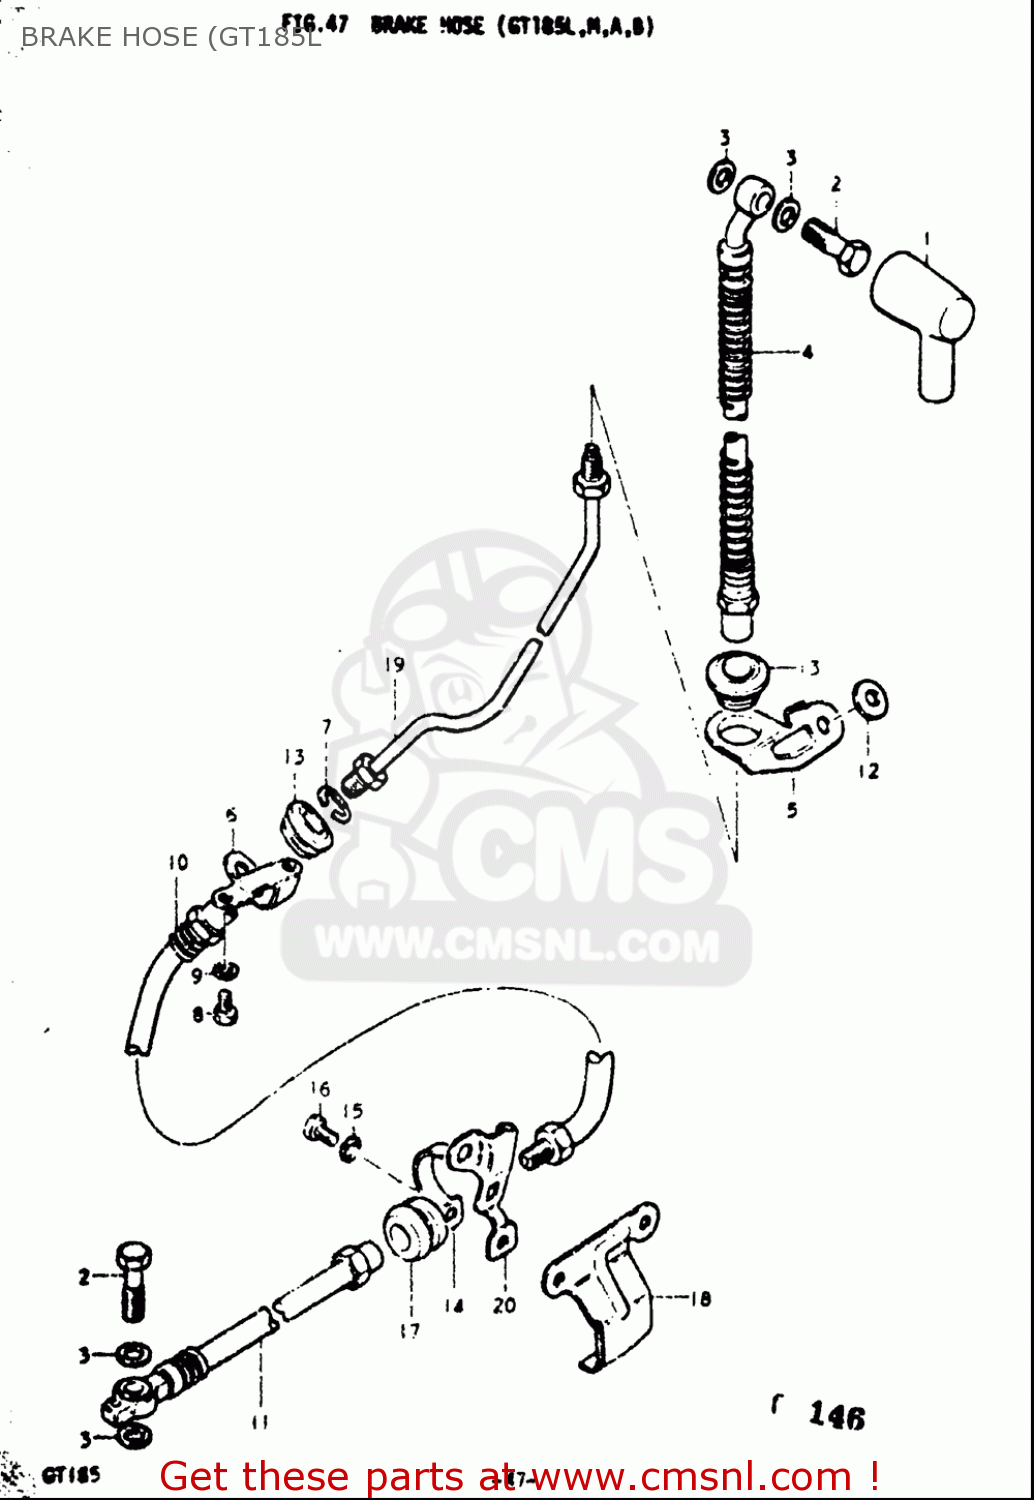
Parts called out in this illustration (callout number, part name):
1	BOOT,MASTER CYLINDER
2	BOLT UNION
3	WASHER(10X15X1.5)
5	GUIDE,BRAKE HOSE
7	E RING
8	BOLT
9	WASHER,LOCK
10	HOSE,BRAKE
11	PIPE,BRAKE
12	WASHER(6.5X14X1.6)
13	GROMMET,BRAKE HOSE GUIDE
15	WASHER,LOCK
16	SCREW(6X12)
17	BUSH
18	COVER, BRAKE HOSE
